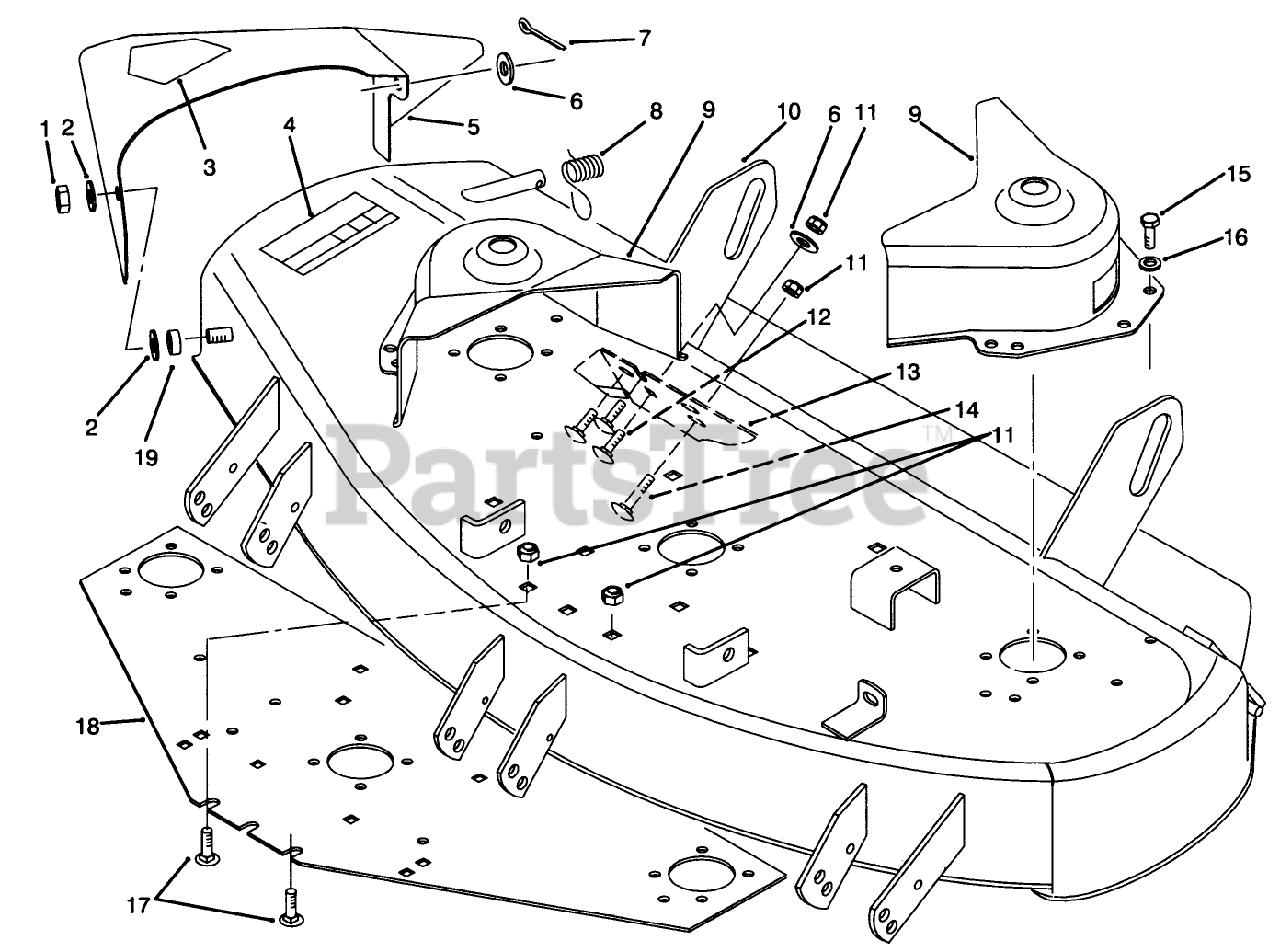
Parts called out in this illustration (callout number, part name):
1	Nut
2	Washer
3	DECAL-DANGER
4	DECAL-DANGER, THROWN OBJECT
5	Chute/Decal Assembly
6	WASHER-FLAT
7	PIN-COTTER
8	Spring
9	COVER-BELT
10	Deck/Safety Decal Assy.
11	NUT-LOCK, NI
12	SCREW-CARR
13	Plate-Wear
14	SCREW-CARR
15	Bolt
16	WASHER-FLAT
17	SCREW-CARR
18	Plate-Deck
19	BUSHING-PIVOT
